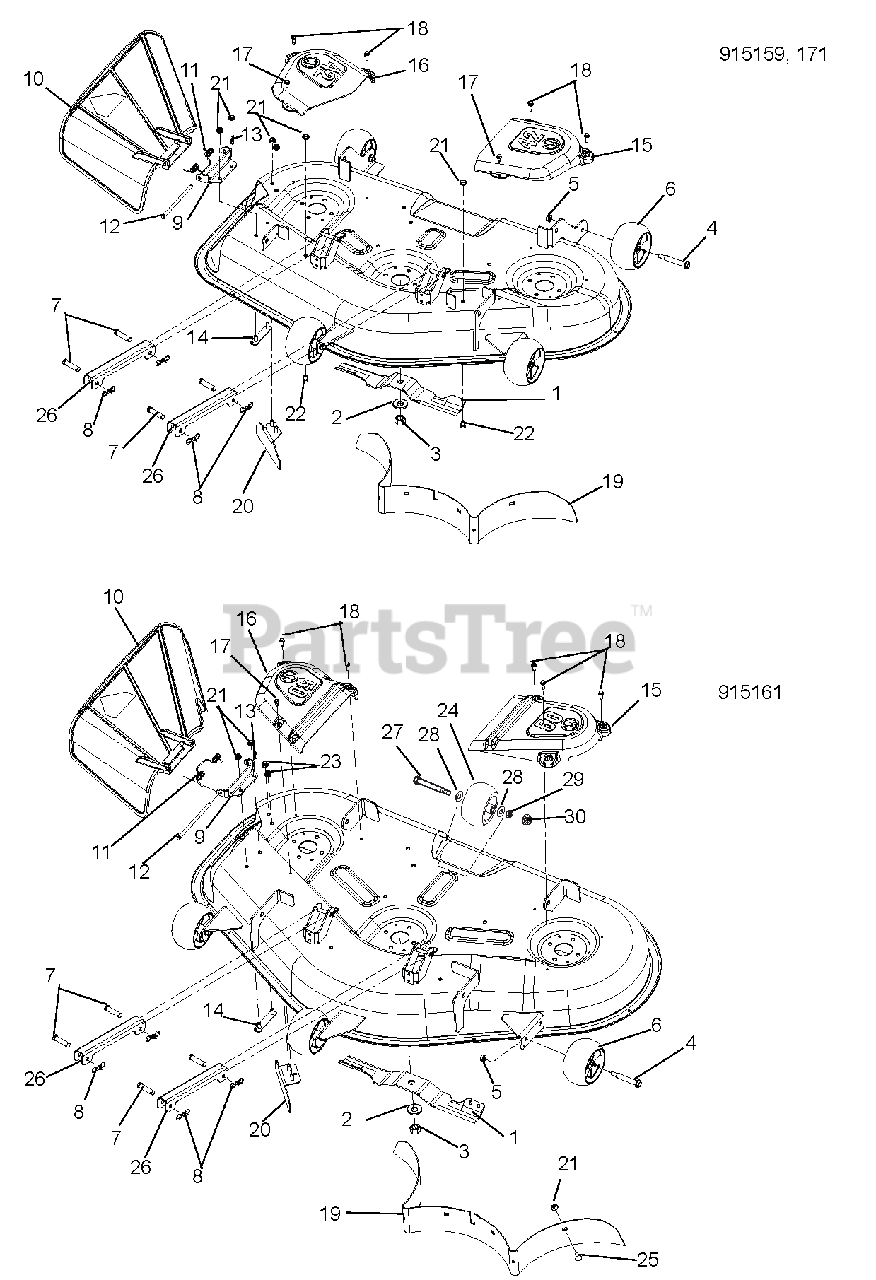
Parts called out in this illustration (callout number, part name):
1	BLADE, MOWER 14.83 (.188 THK)
1	BLADE, MOWER 17.35
2	WSHR-BLVL .669X1.535X.138
3	NUT-HEX .62-18 YWZC
4	BLT-SHLDR .38-16X2.50 HWH G5
5	@NUT-LK-TOP-FLG .38-16 YWZC
6	ANTI-SCALP WHEEL - 5X OS
7	PIN-CLEV .375 X 2.00 YWZC
8	PIN, BOW TIE LOCKING
9	BRKT-DISCHARGE CHUTE MOUNT 42"
9	BRKT, CHUTE MOUNT
10	DISCHARGE CHUTE
11	SPRING-TORSION
12	PIN, 5/16 X 5.80"
13	PIN-HAIR INT .08X.18X1.18 YWZC
14	WMT-DISCHARGE CHUTE MT. STRAP
15	BELT COVER - LH 42"
15	BELT COVER - LH 50"
16	BELT COVER - RH 42"
16	BELT COVER - RH 50"
17	SCR-TAP .25-20X.50 HWH TR YWZ
18	SCR-TAP .25-20X.75 HWH TR YWZ
19	BAFFLE, REAR (42)
19	BAFFLE-50" STAMPED DECK REAR
20	WMT, DISCHARGE BAFFLE (42)
20	BAFFLE, DEFLECTOR (50)
21	@NUT-LK-TOP-FLG .31-18 YWZC
22	@BLT-HEX .31-18X.50 GR5 YWZC
23	@NUT-LK-NYL-FLG .31-18 YWZC
24	ROLLER
25	@BLT-RHDSSQNK .31-18X.75 G5YZ
26	BRKT-STABILIZER LINK
27	@BLT-HEX .38-16X3.50 GR5 YWZC
28	@WSHR-FL-STL.406X.812X.065 YWZ
29	@NUT-LK-CTR-JAM .375-16 YWZC
30	@NUT-LK-NYL-FLG .38-16 YWZC
